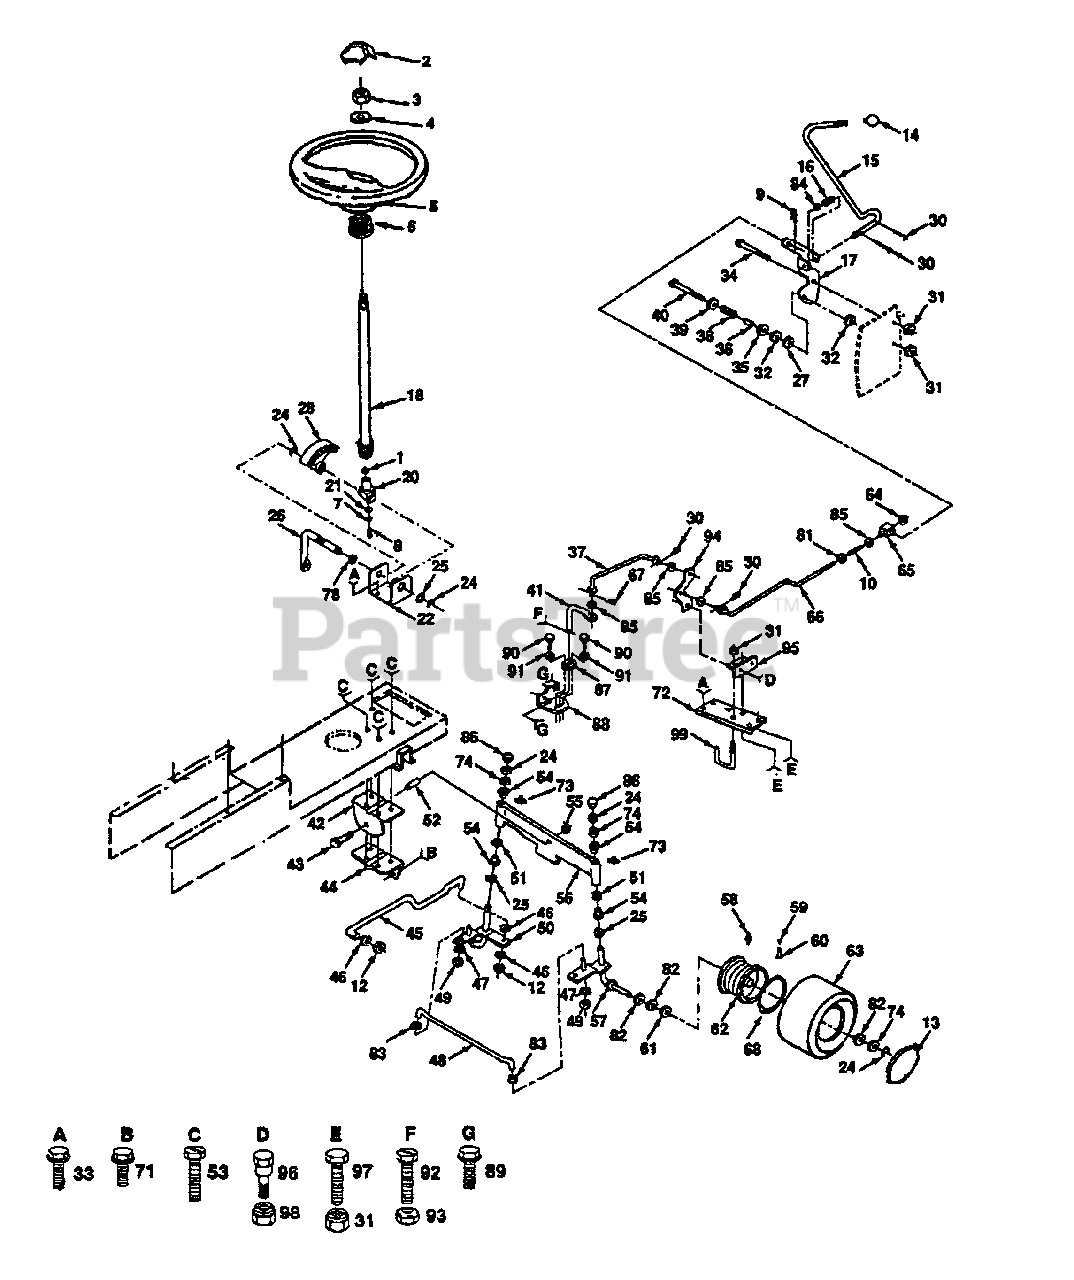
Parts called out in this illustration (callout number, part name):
2	Insert, Steering Wheel
3	Nut, Jam, Toplock 1/2-20
5	Wheel, Steering
6	Adapter, Steering Wheel
7	Washer, Lock 1/4
8	Screw, Socket, Hex 1/4-20 x 5/8
9	Spring, Retainer
10	Spring, Compression
12	Nut, Hex, Fin 3/8-24 UNF
13	Cover, Wheel
14	Knob, Gear Shift
15	Rod, Control
16	Spring, Torsion
17	Bracket, Control Rod
18	Shaft, Steering
20	Support, Shaft
21	Washer, Shim 1/4 x 5/8 x .062
22	Bracket, Steering
24	Ring, Klip
25	Bearing, Thrust
26	Shaft. Pitman
27	Washer, Friction
28	Gear, Sector
30	Pin, Cotter 1/8 x 3/4
31	Nut, Crownlock 3/8-16
32	Spacer, Nylon
33	Screw, Hex Washer Thread Rolling 3/8-16 x 3/4
34	Bolt, Hex Shoulder 3/8-16 x 1-3/8
35	Washer 21/32 x 1-1/4 x 16 Gauge
37	Link, Control, Pump
38	Spring, Compression
39	Washer 13/32 x 1-1/4 x 12 Gauge
40	Bolt, Hex 3/8-16 x 3
41	Lever, Pump Control
42	Support, Saddle, Rear
43	Bolt, Hex 5/8-11 x 3-3/4
44	Support, Saddle, Front
45	link, Drag
46	Washer, Lock 3/8
47	Washer, Lock 5/16
48	Rod, Tie
49	Nut, Hex 5/16-24 UNF
50	S ndle, LH. Washer
51	27/32 x 1-1/4 x 16 Gauge
52	Spacer, Bearing
53	Screw, Special 3/8-16 x 3/4
54	Bearing
55	Nut, Jam Lock Hex W/Washer 5/8-16
56	Axle, Front
57	Spindle, R.H.
58	Fitting, Grease
59	Stem Valve
60	Cap, Valve
61	Bearing
62	Rim, Front
63	Tire, Front
64	Locknut, Hex, w/Wsh. 3/8-16
66	Rod. Control, Adjustable
67	Clip, Hairpin
68	Tube, Tire Front
71	Screw, Hex Washer Thread Rolling 5/16-18 x 1/2
72	Bracket, Chassis, Reinforcement, Hydra
73	Fitting, Grease
74	Washer 25/32 x 1-5/8 x 16 Gauge
78	Nyliner, Snap-in
81	Washer 13/32 x 3/4 x 12 Gauge
82	Washer 25/32 x 1-1/4 x 16 Gauge
83	Washer 11/32 x 3/4 x 16 Gauge
84	Washer 15/32 x 15/16 x 16 Gauge
85	Washer, Spring
86	Cap, Spindle
87	Guide, Control
88	Bracket, Control Guide
89	Screw, Hex Washer Thread Rolling 5/16-18 x 3/4 Type TT
90	Screw, Tap Hex Hd. #10-24 UNC x 1/2 Type T
91	Washer 7/32 x 1/2 x 16 Gauge
92	Screw, Hex Socket Hd. #10-24 UNC
93	Locknut #10-24 UNC
95	Bracket, Bellcrank, Pivot
96	Bolt, Shoulder
97	Bolt. Hex, Fin 3/8-16 UNC x 1
98	Nut, Crownlock 5/16-18
99	Keeper, Centerspan
